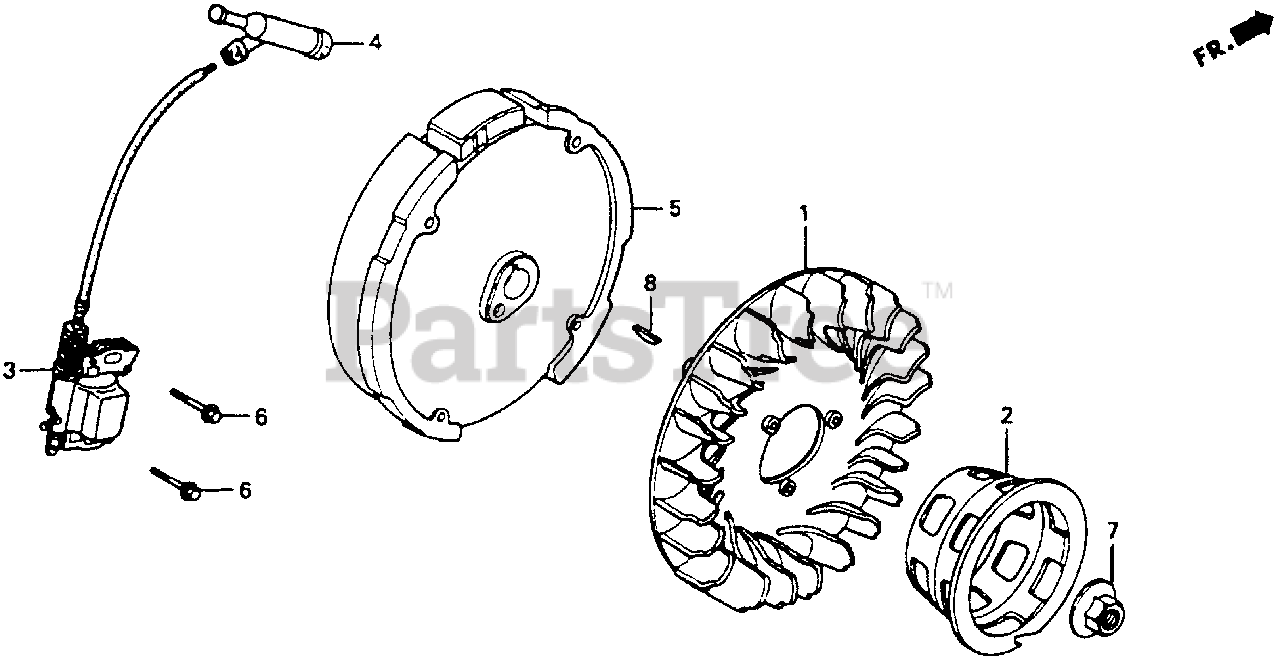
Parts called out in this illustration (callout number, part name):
1	FAN, COOLING
2	PULLEY, STARTER
3	COIL ASSY., IGNITION
4	CAP ASSY., NOISE SUPPRESSOR (NICHIWA Y-EZ RTFM256)
5	FLYWHEEL
6	BOLT, FLANGE (6X28)
6	BOLT, FLANGE (6X25) (CT200)
7	NUT, SPECIAL (14MM)
8	KEY, SPECIAL WOODRUFF (25X18)
